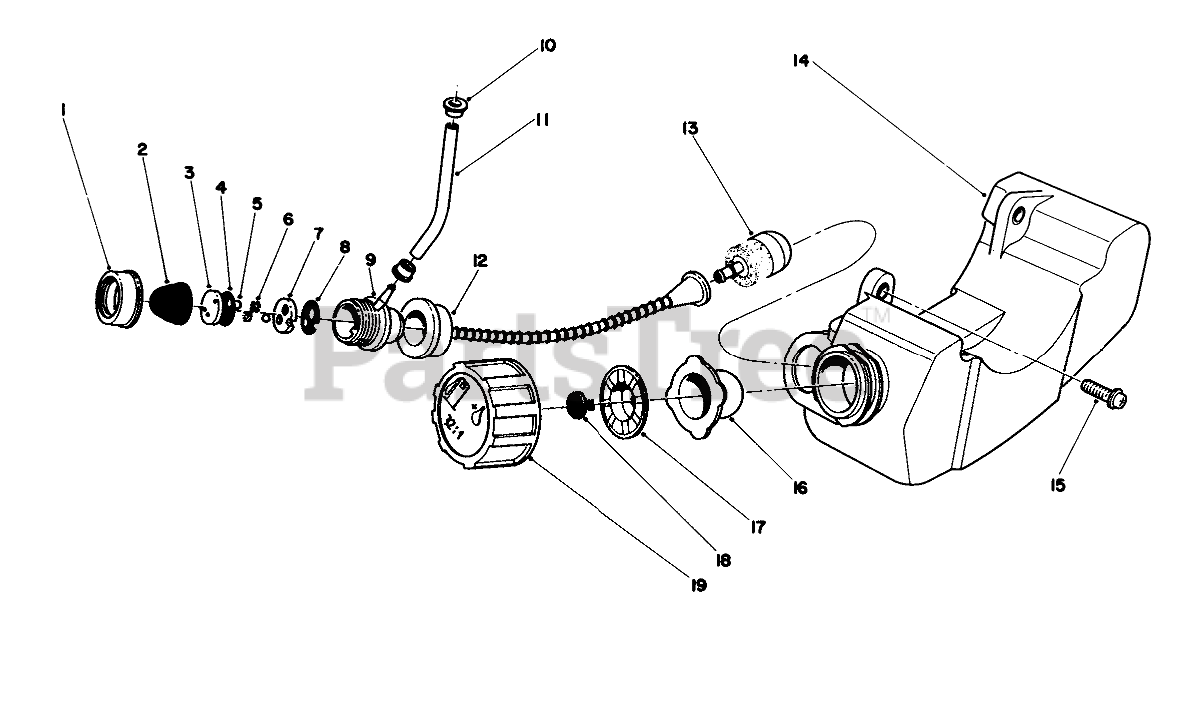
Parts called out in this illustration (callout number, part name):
8	GASKET
9	PRIMER PUMP
13	FUEL FILTER
16	GASKET - PACKING
17	HOLDER
18	BREATHER VALVE
19	TANK CAP
